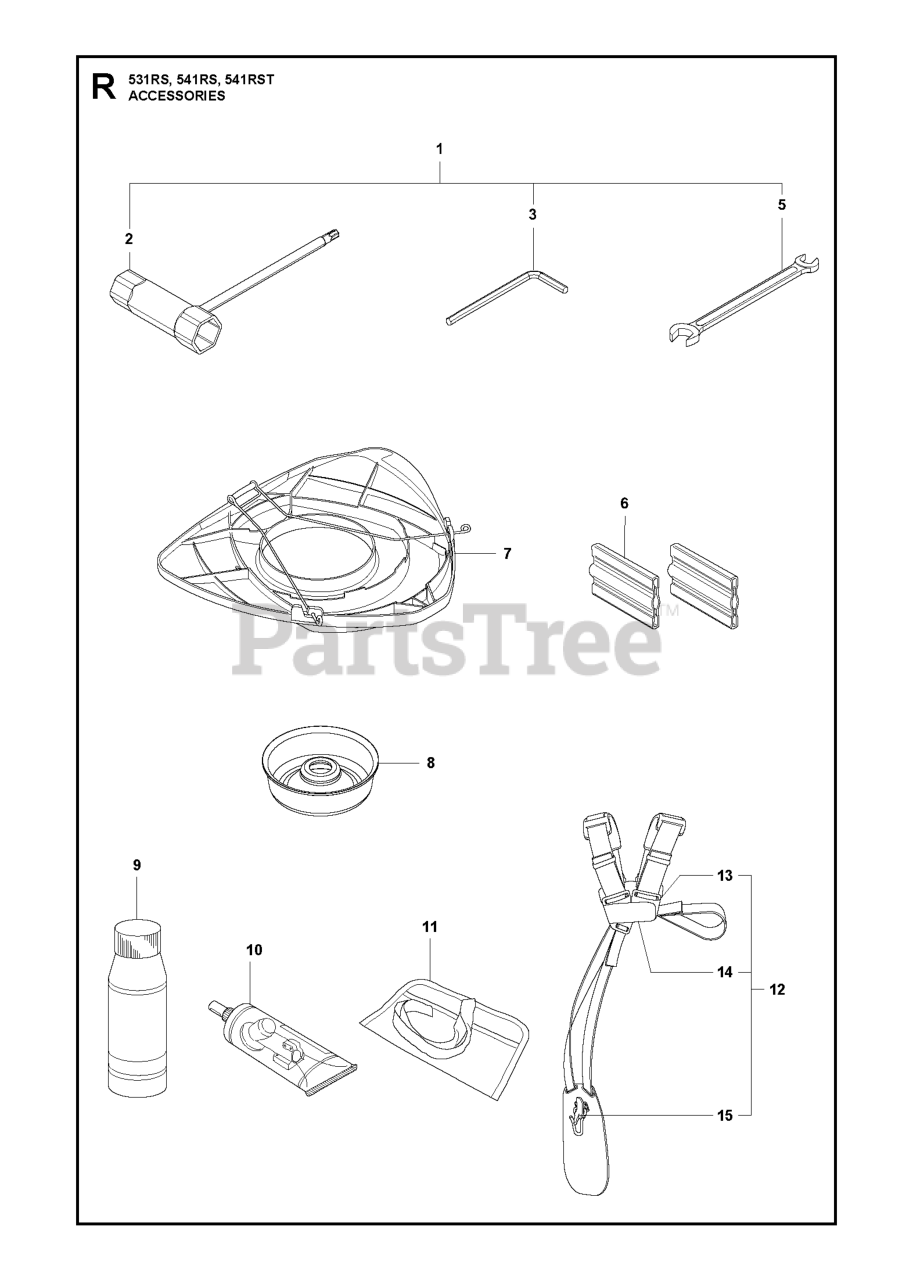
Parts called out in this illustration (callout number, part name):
5	WRENCH SPANNER
6	BAR GUARD
7	TRANSPORT GUARD
8	SUPPORT CUP
9	Air Filter Oil 1l.
10	BEVEL GEAR GREASE
12	Harness
13	FRONT PIECE
14	FRONT PIECE
